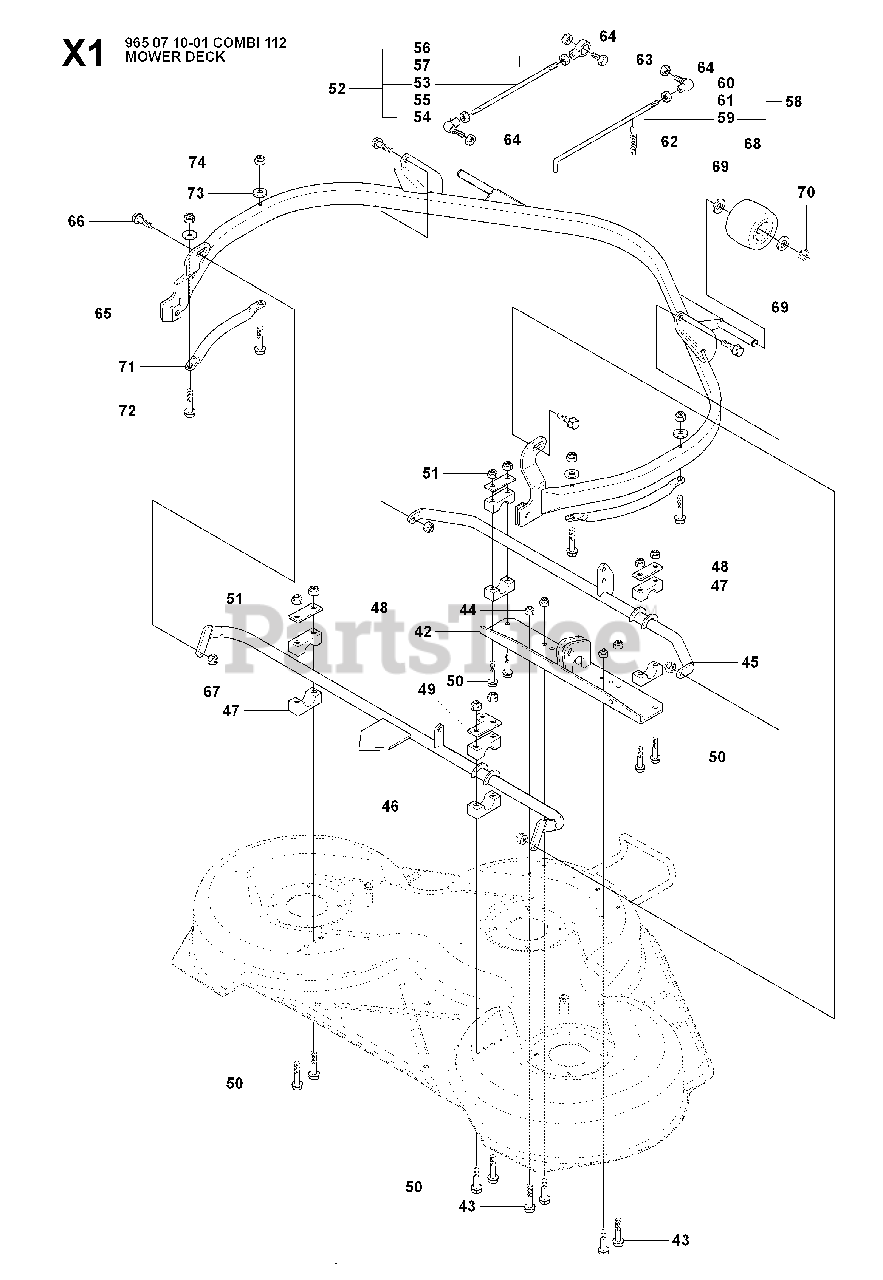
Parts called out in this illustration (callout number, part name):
44	LOCKNUT M8
51	LOCKNUT M8
52	PARALLEL RODY ASSY
58	CLUTCH ROD ASSY
67	LOCKNUT M8
68	DECK ROLLER, FRONT
70	RETAINING RING SGA 15
73	WASHER
74	LOCKNUT M6
